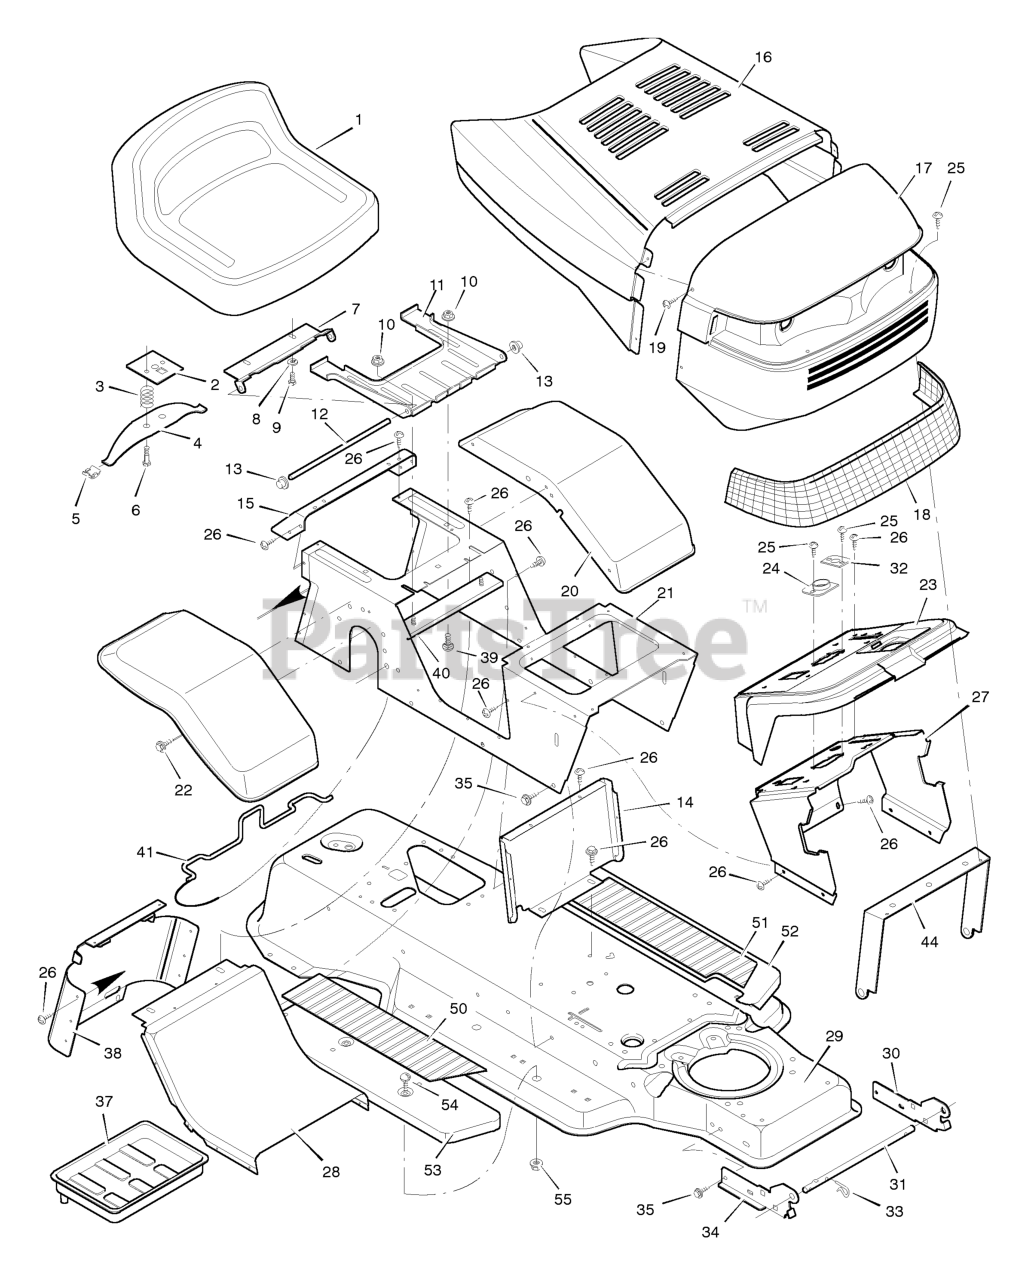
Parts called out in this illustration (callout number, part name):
2	Plate Assembly, Switch
3	Spring, Compression
4	Spring, Seat
5	Glide, Spring
6	Bolt, Shoulder
7	Support, Seat
8	Lockwasher
9	Bolt, Hex
10	Locknut, Flange
11	Bracket, Pivot
12	Rod, Pivot
13	Cap, Push On
14	Insert, Front
15	Fender, Apron
17	Grille Assembly
21	Console Assembly
23	Dash Panel
24	Bearing, Steering
26	Screw
27	Support, Dash
28	Insert, Rear
29	Frame Assembly
30	Bracket, Left Grille
31	Rod, Pivot
32	Bearing
33	Pin, Hair
34	Bracket, Right Grille
37	Tray, Battery
38	Cap, Console
39	Bolt
40	Channel Assembly
41	Clamp, Battery
44	Brace, Grille
46	Bolt, Hex
50	Mat, Right
51	Mat, Left
52	Running Board, Left
53	Running Board, Right
54	Bolt, Carriage
55	Nut, Flange
